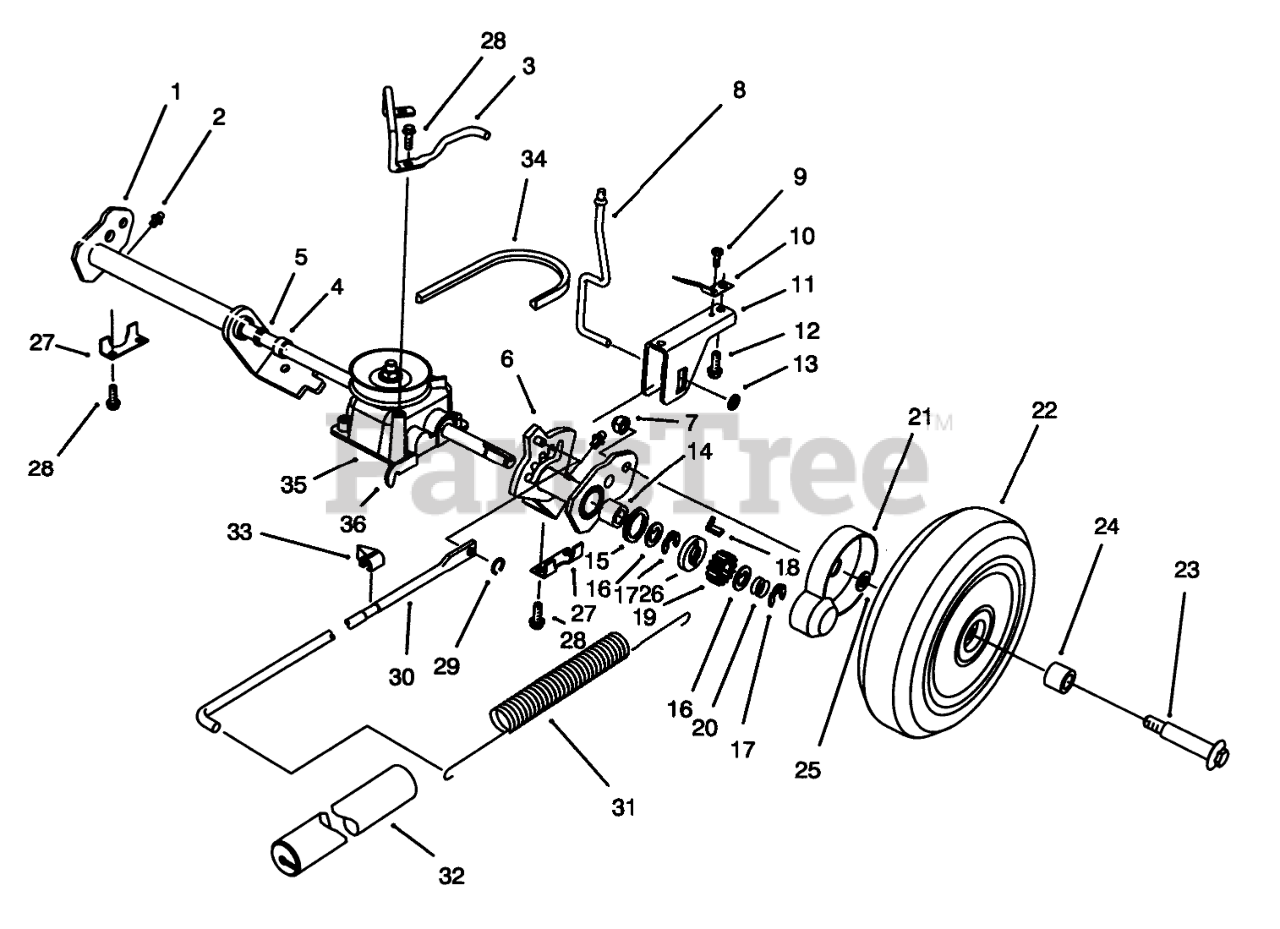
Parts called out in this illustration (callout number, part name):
1	Rear Pivot Assembly R.H. (Incl. Ref. #2, 4, 5 & 14)
2	FITTING-GREASE
3	Retainer Belt
4	BUSHING
5	SEAL-OIL
6	Rear Pivot Assembly L.H. (Incl. Ref. #2, 4, 5 & 14)
7	NUT-HEX
8	TRIGGER ROD
9	SCREW 8 - 32 X 250
10	SPRING - TRIGGER RET
11	SADDLE - HOC
12	SCREW
13	PUSHNUT
14	BEARING-ROLLER
15	RING-FRICTION
16	WASHER-THRUST, KEYED
17	RING-CLIP, LOCKING
18	KEY-ROCKING, LH
19	GEAR-PINION
20	SPRING-COMPRESSION
21	COVER-WHEEL
22	Wheel, Tire & Gear Assy. (Incl. Ref. #24)
23	BOLT-WHEEL
24	BUSHING
25	SPACER-COVER, WHEEL
26	WASHER-CLUTCH
27	REAR SECURING PLATE
28	SCREW-HWH
29	GRIP RING
30	LINK ROD
31	SPRING-COUNTERBALANCE
32	COVER-SPRING
33	INDICATOR-HEIGHT OF CUT
34	V-BELT
35	Gearcase Assembly (Incl. Ref. #36)
36	Bracket-Traction
